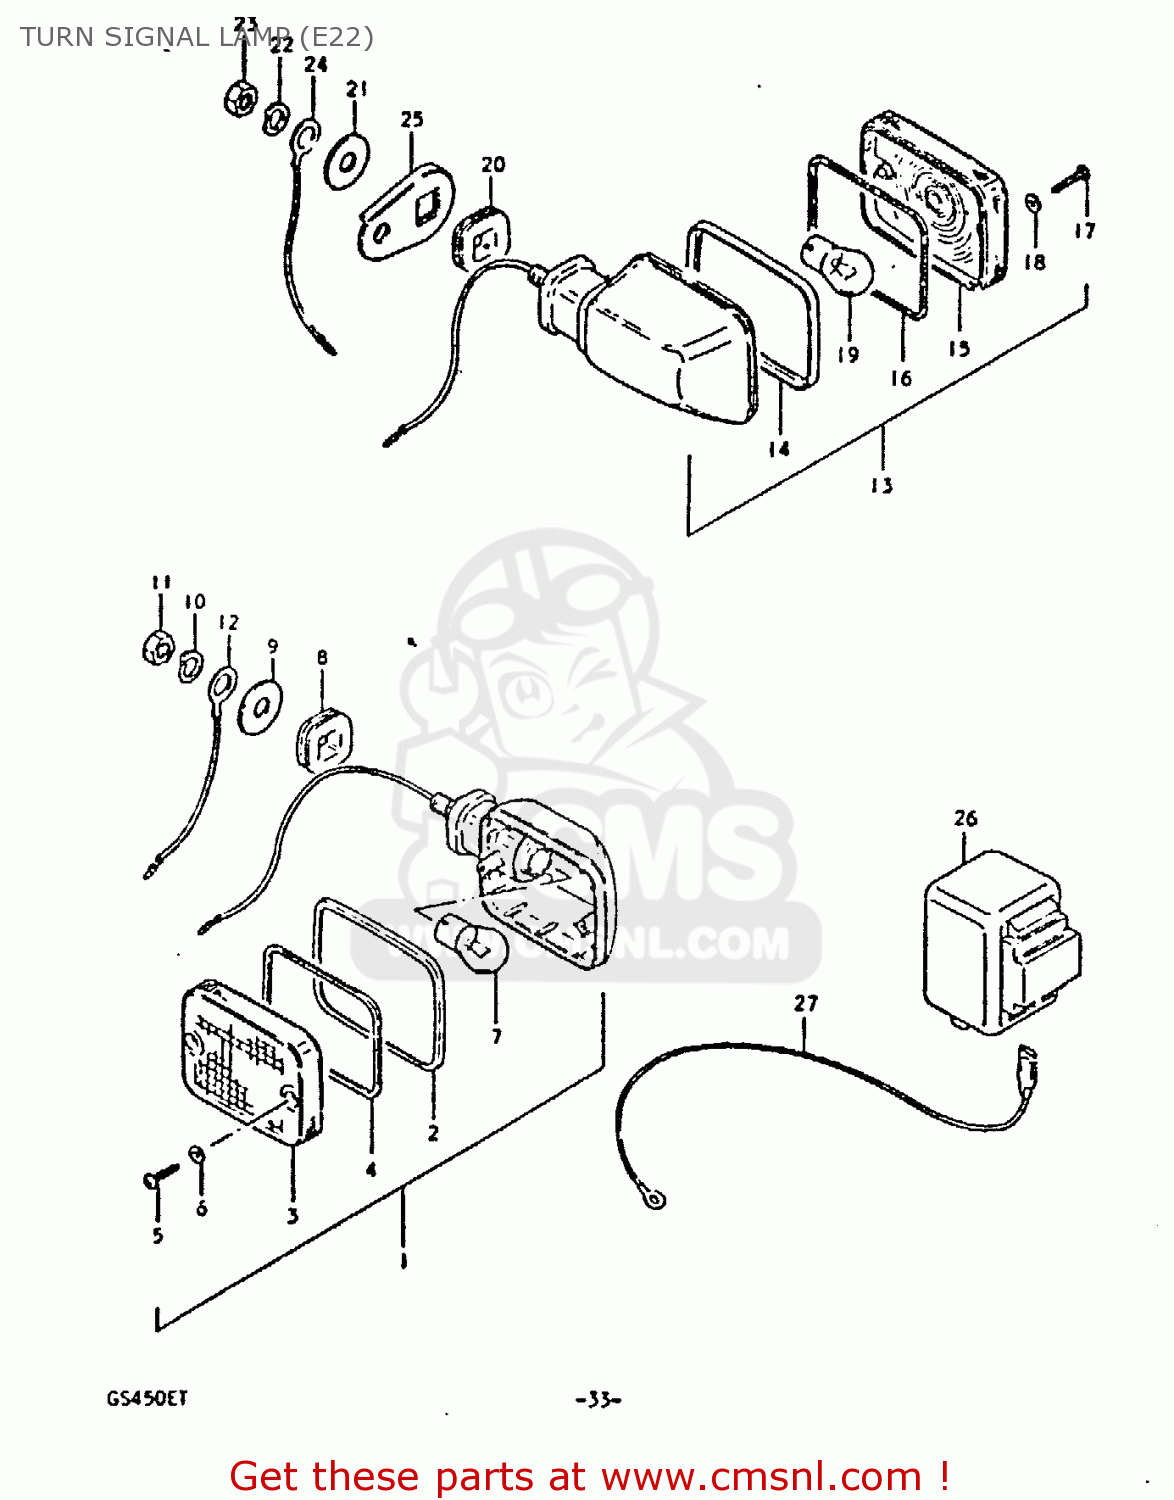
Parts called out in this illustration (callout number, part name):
1	LAMP ASSY, FRONT TURN SIGNAL
2	RIM
3	LENS
4	GASKET (NAS)
5	SCREW
6	GASKET (NAS)
7	BULB(12V21W)
8	CUSHION
9	WASHER (10.5X30X2.3)
10	LOCK WASHER
11	NUT
12	LEAD WIRE,EARTH
13	LAMP ASSY, REAR TURN SIGNAL
14	RIM
15	LENS
16	GASKET (NAS)
17	SCREW
18	GASKET
19	BULB(12V21W)
20	CUSHION
21	WASHER (10.5X30X2.3)
22	LOCK WASHER
23	NUT
24	LEAD WIRE,EARTH
25	BRACKET,RR TURN SIGNAL LAMP
26	RELAY, TURN SIGNAL
27	LEAD WIRE, RELAY EARTH
